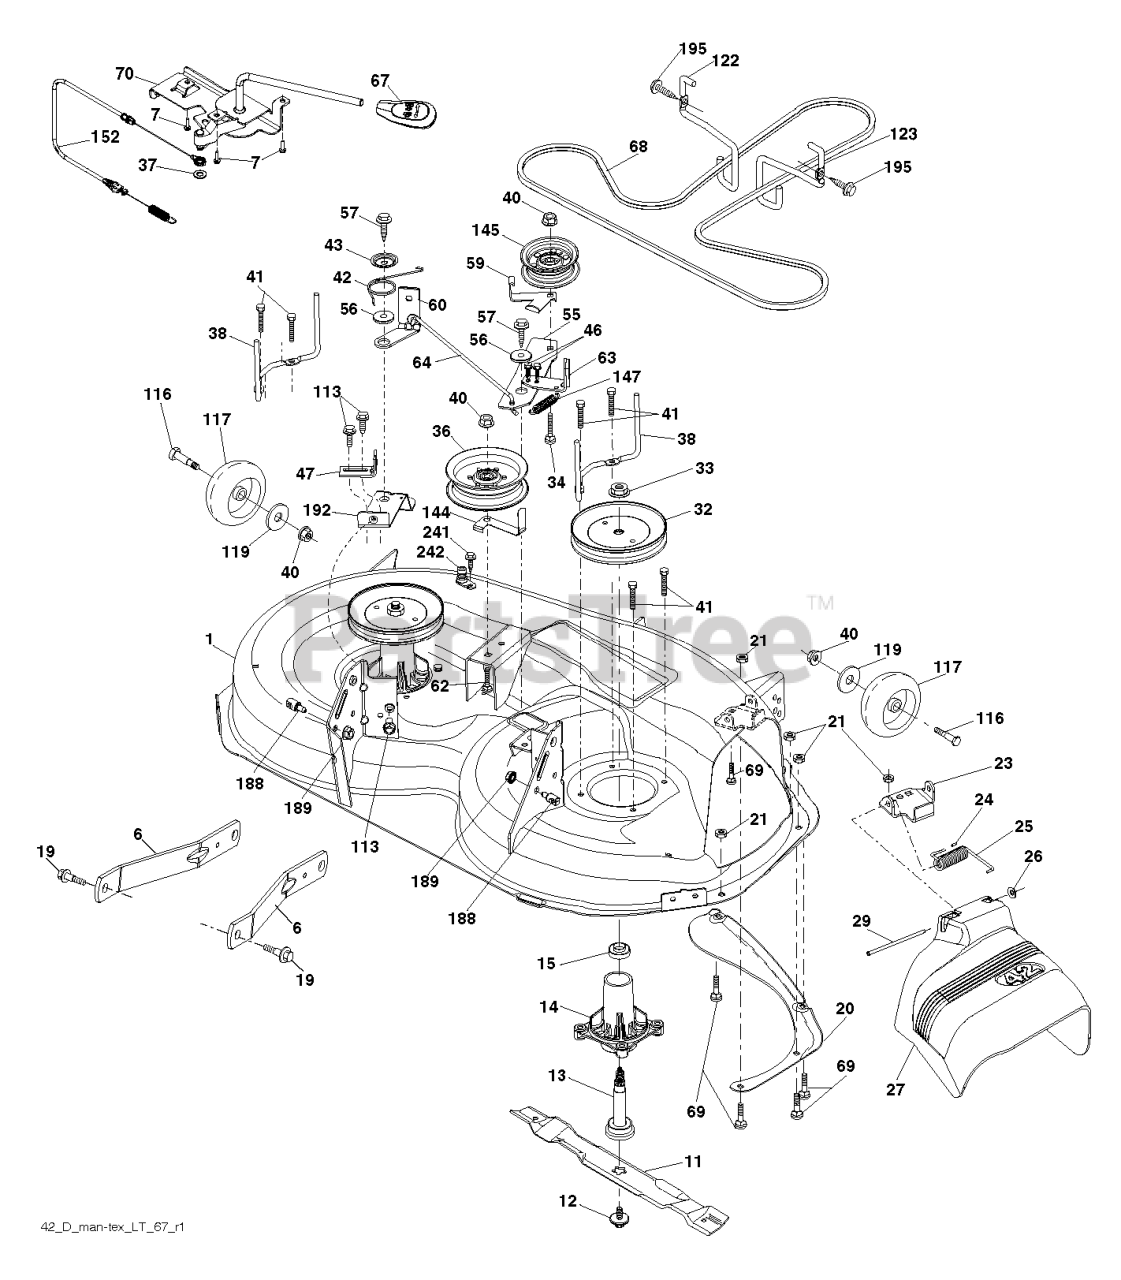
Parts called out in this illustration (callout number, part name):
1	DECK.WELDMNT.42"GREYMS498
1	DECK.SVC.42"2GW
6	ARM.SUSPENSION.MOWER.R
7	SCREW.#10 X 0.750.BOS
11	42" HI-LIFT BLADE
12	SCREW.SEMS.7/16-20X1.HEX.HEAD
13	SHAFT ASM.MNDRL.N/GREASEABLE
14	RP.HOUSING.MANDREL.4PT.
15	BEARING
15	BEARING.MANDREL.TOP.EXTENDED
19	BOLT.SHOULDER
20	BAFFLE.VORTEX
21	LOCKNUT
23	BRKT.DEFLECTOR.38"2005+
24	CAP-SLEEVE LT
25	SPRING.TORSION.DEFLECT
26	NUT PUSH M
27	SHIELD.DEFLECTOR.MOWER.42"BLAC
29	ROD.HINGE
32	PULLEY.MANDREL.5.0.PD.38"
32	PULLEY.MANDREL.5.438.PD
33	NUT.FLANGE.LOCK.TOP
34	BOLT.3/8-16X1.50
36	PULLEY.IDLER.2006
37	WASHER
38	KEEPER.BELT.MANDREL.PULLEY
38	KEEPER.BLT.PNT.MNDRL.PULL.6.25
40	NUT LOCK FLG 3/8-16 UNC
41	BOLT.HEX.WASHR.HED.313-18X1.19
42	SPRING.TORSION.BRAKE
43	SRPING.TORSION.RETAINE
46	SCREW.1/4-20X5/8
47	BRKT.CLUTCH.CABLE
55	IDLER.ARM
55	IDLER.ARM.42"
56	SPACER.RETAINER
57	SCREW 3/8-16X1
59	GUARD, BELT
60	ARM BRAKE MOWER
63	ARM.BRAKE.ZINC
63	ARM BRAKE MOWER
64	LINKAGE.BRAKE.ASM.ZINC
67	HANDLE.CLUTCH.CABLE.LT
68	BELT.DECK.DRIVE.42"
69	BOLT
70	CLUTCH.ASM.MANUAL.YT.PREDATORQ
70	CLUTCH.ASM.CABLE.HUSQ.TEX
113	BOLT.5/16HEX.WHS.HD
116	BOLT M
117	WHEEL.GAGE.HALF.SPOKED
119	WASHER.5/16.FLAT.STE.STD.
122	KEEPER BELT ENGINE LH
123	KEEPER BELT RH
144	KEEPER.BELT.MOWER
145	PULLEY.IDLER.48"PRIMARY
147	RETURN SPRING
152	CABLE.CLUTCH.CABLE.W/SPRING
152	CABLE.MECHANICAL.CLUTCH
188	STUD.FASTNER.W/ANTI-ROTATE
189	NUT LOCK HEX FLANGE 5/16-18
192	BRKT.BRAKE.STAND.LH.
195	SCREW, 3/8-16X3/4
241	SCREW.TT.#10-32X.5.3/8.FLANGE
242	PORT.WASHOUT
